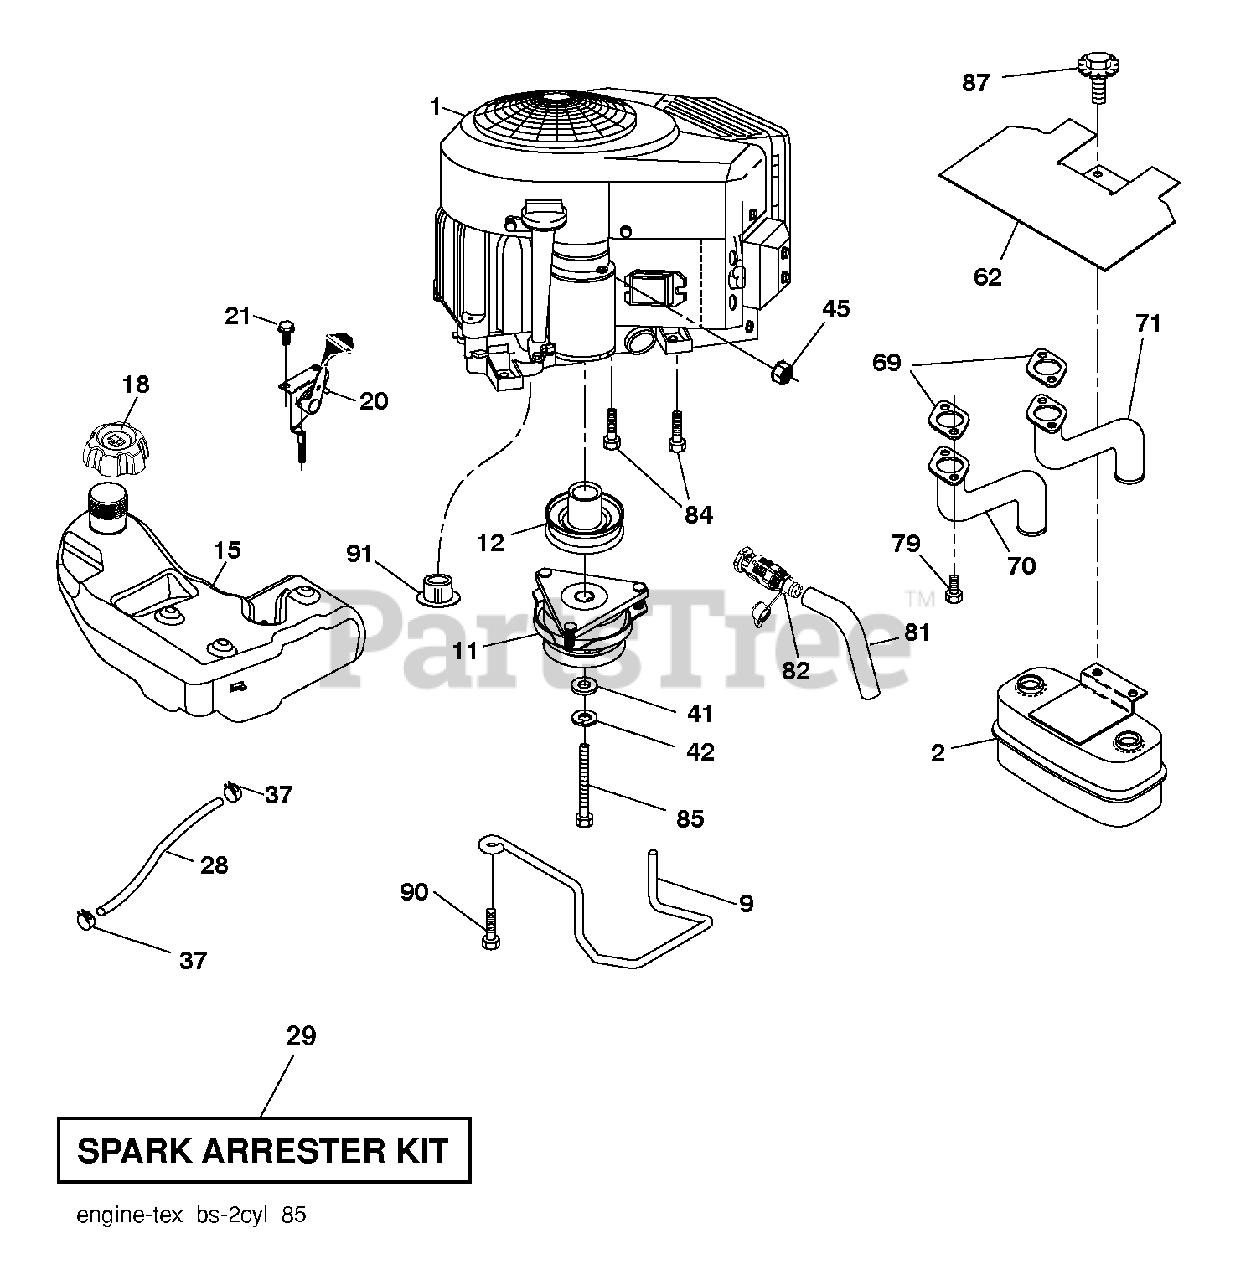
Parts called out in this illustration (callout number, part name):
2	MUFFLER.TWIN.CYL.LOW.TONE
9	KEEPER.BELT.ENGINE.4.2
11	CLUTCH ELECTRIC
12	PULLEY ENGINE
15	TANK.ASM.4.GAL.EPA.ONE.PORT
18	CAP ASM.FL.RTCHT.3"GRY.E10
20	CONTROL.TH/CK.COBRA.B&S.TWN.
21	SCREW.#10 X 0.750.BOS (2 2)
28	LINE.FUEL.64"REAR.EMIS
29	KIT.SPARK ARRESTOR(392390 B&S)
37	HOSE CLAMP
42	LOCKWASHER
45	NUT
62	SHIELD.HEAT.MUFFLER
69	GASKET.MUFFLER
70	RP.EXHAUST.TUBE.LH.BS/TWIN
71	RP.EXHAUST.TUBE.RH.BS/TWIN
79	SCREW.SOCKET.HEAD.5/16-18
81	TUBE, DRAIN OIL ASM.
82	VALUE.OIL.DRAIN
84	SCREW.3/8-16
85	BOLT HEX 7/16-20 X 3.75 GR. 5
87	BOLT.5/16-18UNCX1.W/SEMS.BLK
90	SCREW 3/8-16X1
91	BUSHING.1.375OD
